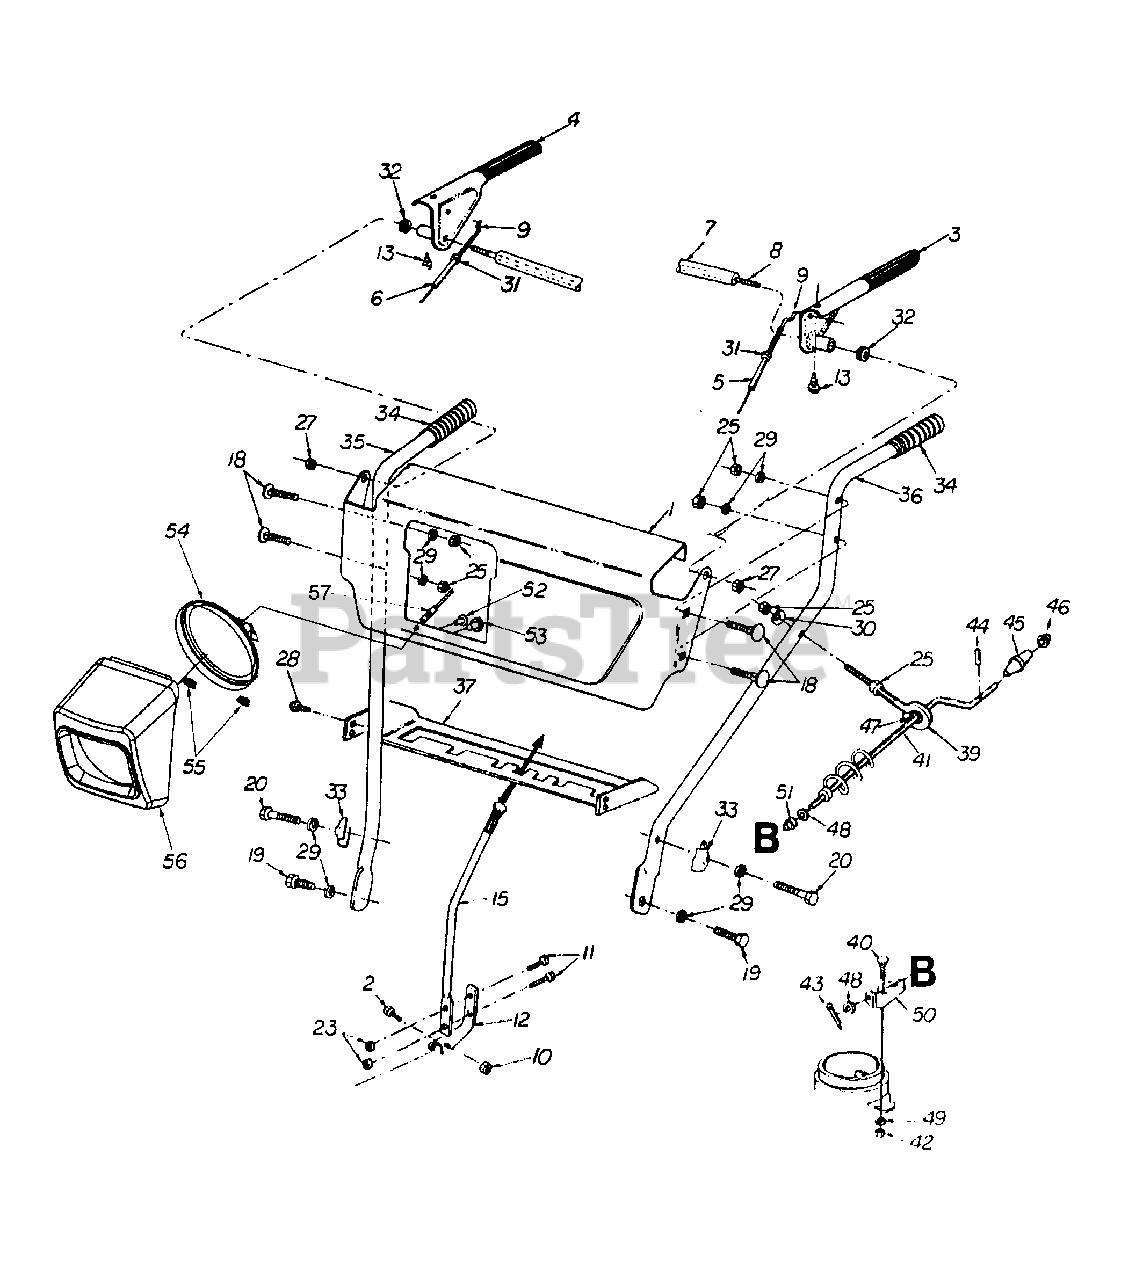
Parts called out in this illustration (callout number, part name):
2	Hex Bolt 1/4-20 x 1.00
3	Clutch Lever LH
4	Clutch Lever RH
5	Auger Clutch Cable
6	Drive Clutch Cable
7	Pivot Rod Cover Tube
8	Clutch Lever Pivot Rod
9	"Z" Fitting
10	Hex Nut 1/4-20
11	Hex Scr. 1/4-20 x .75
12	Shift Lever Spring
13	Rubber Bumper
15	Shift Handle (w/grip)
18	Carriage Bolt 5/16-18 x 1.50
19	Hex Bolt 5/16-18 x .75
20	Hex Bolt 5/16-18 x 1.75
23	Hex Ins. L-Nut 1/4-20
25	Hex Cent. L-Nut 5/16-18
27	Hex Ins. L-Nut 5/16-18
28	Hex Wash Hd B-Tapp Scr. 1/4-20 x .50
29	L-Wash 5/16 ID
30	Bell. Washer .345 ID x .88 OD x .06
31	Hex Nut 10-24
32	Spacer
33	Handle Tab
39	Eyebolt Chute Crank
40	Carriage Bolt 5/16-18 x .75
41	Chute Crank Ass'y
42	Hex Center L-Nut 5/16-18
43	Int. Cotter Pin 5/16 Dia.
44	Roll Pin .125 Dia. x .62
45	Knob-Chute Crank
46	Cap Speed Nut 3/8
47	Grommet
48	Flat Washer .385 ID x .62 OD
49	Flat Washer .344 ID x .875 OD
51	Plastic Bushing .380 ID
52	Truss Machine Tapp Scr.
53	Scr:AB:1/4-14:.625: Hxindwsh
54	Headlight 18 Watts
55	Hex Nut .250
56	Headlight Bezel #8
57	Harness (Round Light)
